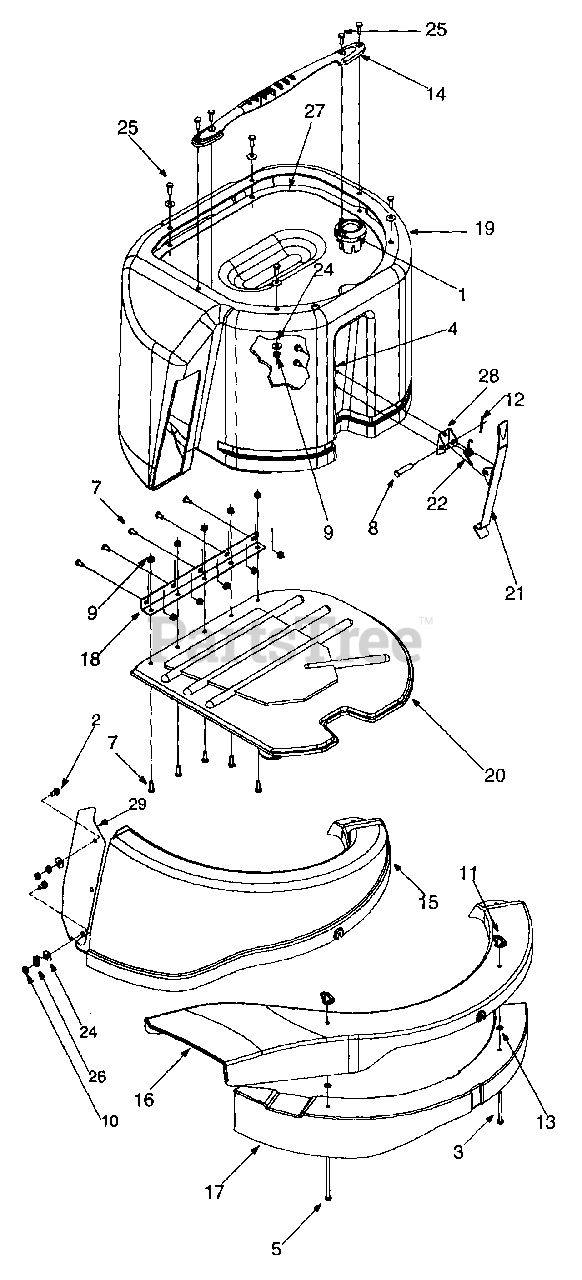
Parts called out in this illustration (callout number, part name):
1	Flow indicator
2	Truss Mach. Scr. 1/4-20 x .50
3	Hex Bolt 1/4-20 x 2.75"
4	Hex washer TT Scr. 1/4-20 x .75
5	Hex Bolt 1/4-20 x 3.75"
7	Pan Head Mach. Scr. 1/4-20 x .75
8	Clevis Pin
9	Sems Hex Nut 1/4-20
10	Hex Jam Nut
11	Wing Nut
12	Cotter Pin
13	Pushnut Fastener
14	Bag Handle
15	Discharge Chute
16	Side Discharge Chute
17	Mulch Plug
18	Grass Bag Hinge
19	Grass Bag
20	Grass Bag Cover
21	Bag Release Lever
22	Torsion Spring
24	Flat Washer .28 I.D. x .74 DE x 0.63
25	Pan Hd. Mach. Scr. 1/4-20 X 1.0
26	Lock Washer
